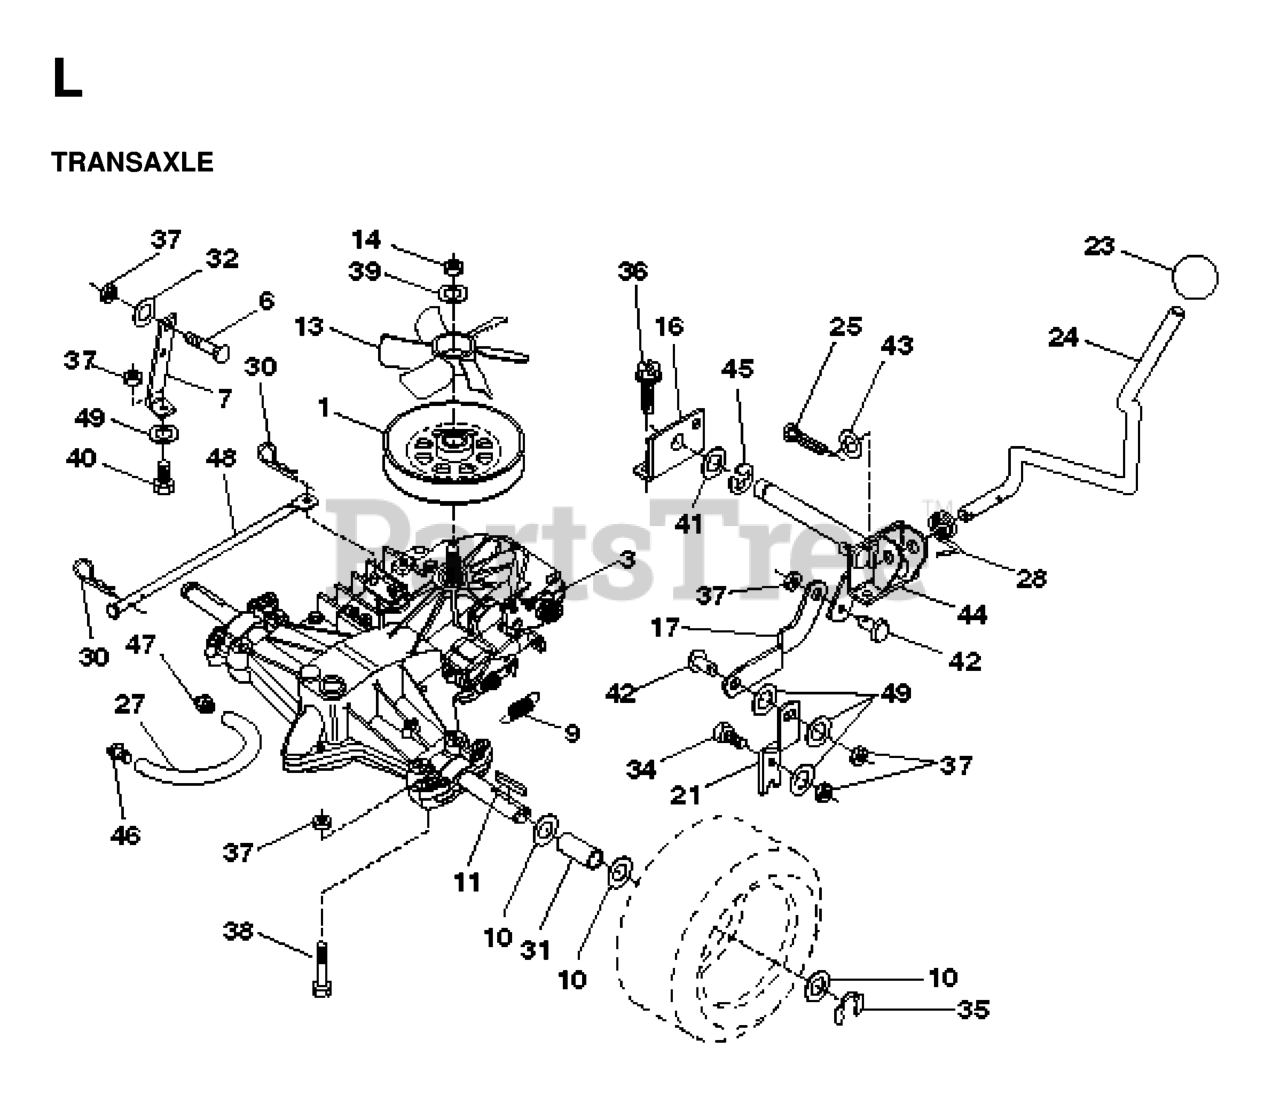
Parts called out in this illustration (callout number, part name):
1	PULLEY.V-GROOVE
3	TRANSAXLE.HYDRO.319-0500.LR
6	RP BOLT 5/16-18 X3/4 ZN/YEL GR
9	SPRING,BRAKE RETURN
11	SQUARE KEY
13	FAN.TRANSMISSION.HYDRO.6"
16	SUPPORT, SHIFT HANDLE
17	LINK, SHIFT
21	LEVER, SHIFT
23	KNOB.DUCKHEAD.1/2
24	ROD, SHIFTER
25	PIN COTTER
27	LINE FUEL HYD 4"
28	SPRING, TORSION
30	RETAINER M
31	SPACER SPLIT
34	BOLT RB
36	SCREW
37	NUT.71038.31-18.HEX.NYLOCK
40	BOLT
41	Washer 21/32 x 1-1/4 x 13 Ga.
43	WASHER
44	PIVOT SHAFT
45	RETAINING RING LT
46	CAP, VENT ASSY
47	O-RING KIT 70110
49	WASHER M
